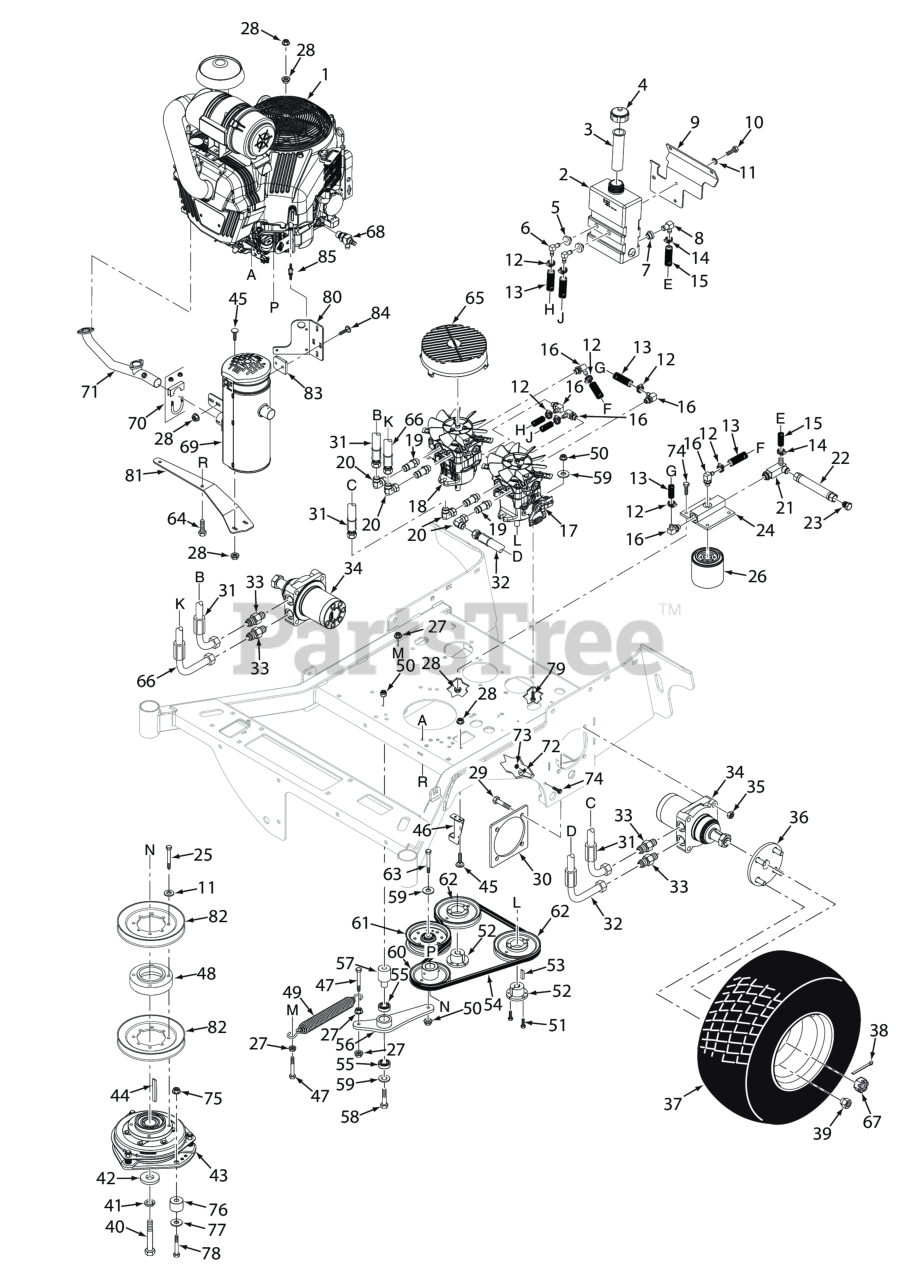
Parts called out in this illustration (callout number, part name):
1	Engine, Briggs & Stratton 37 BV-EFI (61E8770002J1)
2	Hydro Tank Assy., SVRII
3	Insert, Filler Neck
4	CAP, HYDRAULIC TANK
5	Bushing, 0.56" Dia. Viton
6	Elbow, 90 Degree, 9/16-18 JIC x 9/16 O-Ring
7	Bushing, 0.78" Dia. Viton
8	Fitting, 90 Degree - 1/2" Hose
9	Bracket, Hydro Tank Mounting
10	BOLT, SERRATED FLANGE HEX HEAD 5/16-18 X 3/4"
11	Lockwasher, 5/16 (.317 x .586 x .078) Helical Spring
12	Clamp, .69" Max. / .25" Min. Dia.
13	Hose, 3/8" ID - 10-1/4" Long (Order By The Inch)
14	Clamp, Cable 3/4" I.D.
15	Hose Assembly, 1/2" ID (Oil Reservoir to Filter Base)
16	Elbow, 90 Degree - 9/16" O-Ring x 3/8" Hose
17	Pump, LH - SVRII
18	Pump, RH - SVRII
19	Union, O-Ring to JIC
20	Elbow, 1/2 JIC Female to 1/2 JIC Male
21	Tee, 3/4" O-Ring
22	Drain, Hose Assembly
23	Plug, JIC 3/4-16 UNF
24	Filter Head Assembly
25	Bolt, M8-1¼ x ½"
26	OIL FILTER, SPECIAL
27	NUT, 3/8-16 SERRATED FLANGE HEX HEAD
28	Nut, Serrated Flange 5/16-18 (Right Front Engine Mounting, Briggs and Kohler Only)
29	Bolt, Hex Hd. 1/2-13 x 2-1/2" (lower)
30	Plate Weldment, Motor Backing
31	Hose Assy., 27-1/2"
32	Hose Assy., 15-1/4"
33	TUBE UNION, 3/4-16 JIC TO 7/8-14 "O" RING
34	Wheel Motor, SVRII
35	Locknut, Hex 1/2-13 Center Lock
36	Wheel Hub Assy., SVRII
37	Wheel Assembly, 24 x 12-12 (SPZ61)
38	Pin, Cotter 9/16" x 1-1/2"
39	Wheel Nut, 1/2-20 x 13/16
40	Bolt, Hex Head 7/16-20 x 3" w/t Patch
41	Lockwasher, 7/16� Spring
42	Flatwasher, 7/16-.469 x 1.75 x .25 (48, 52)
43	Clutch, GT3.5 (28.6mm Bore)
44	Key, 1/4 x 1/4 x 3-1/2"
45	Bolt, 5/16-18 x .75 RHSN Carriage
46	Bracket, Anti-Rotation
47	Bolt, Hex Head 3/8-16 x 1-1/2" Grade 8 Black
48	Hub, Clutch Pulley
49	Spring, Transmission Drive
50	HEX NUT, ELASTIC STOP LOCK, 3/8-16
51	Bolt, Hex Head 1/4-20 x 1" Grade 8 Black
52	Hub, Tapered, 15mm Bore
53	KEY, 5 MM X 5 MM X 25 MM
54	Belt, Pump Drive (37BV-EFI)
55	BEARINGS, BALL, NEUTRAL RETURN
56	Idler Arm Assy.
57	Pivot, Idler
58	Capscrew, Hex Head 3/8-16 x 3.25"
59	Flatwasher, 3/8 (.391 x .938 x .105 HD) Grade 8
60	Pulley, 4.75" DIA 1.125 DIA Bore
61	Pulley, Idler 4-1/2"
62	Pulley, 5.45 OD - Tapered Bore"
63	Bolt, Hex Head 3/8-16 x 2-1/4" - 61"
64	Bolt, Hex Head, 3/8-16 x 1-1/2"
65	Fan Cover, Pump
66	Hose Assy., 30"
67	Nut, Hex Castle 1.0-20 UNEF
68	Oil Drain, 35BV & 37BV-EFI - Briggs & Stratton
69	Muffler, 37BV-EFI
70	Clamp, Muffler (Clamp Only)
71	Manifold, 37 BV-EFI
72	Clamp, Cable 3/4" ID.
73	Nut, Flange Head Elastic Stop 5/16-18
74	Bolt, Heax Head 5/16-18 x 1" (48V / 52V)
75	HEX NUT, ELASTIC STOP LOCK, 5/16-18
76	Bushing, UHMW
77	Flatwasher, 5/16-.375 x .875 x .083 (35BV & 37BV-EFI)
78	Bolt, Hex Head 5/16-18 x 1-1/2" (Right Front Engine Mounting, Briggs and Kohler Only)
79	Bolt, Hex Head, 3/8-16 x 1-1/2"
80	Muffler Bracket, Valve Cover
81	Muffler Bracket, Engine
82	Pulley, Clutch 7.30 DIA
83	Strap Spacer, Muffler
84	Bolt, Carriage 5/16-18 x 1-1/4"
85	Stud, Valve Cover Exhaust Mount
